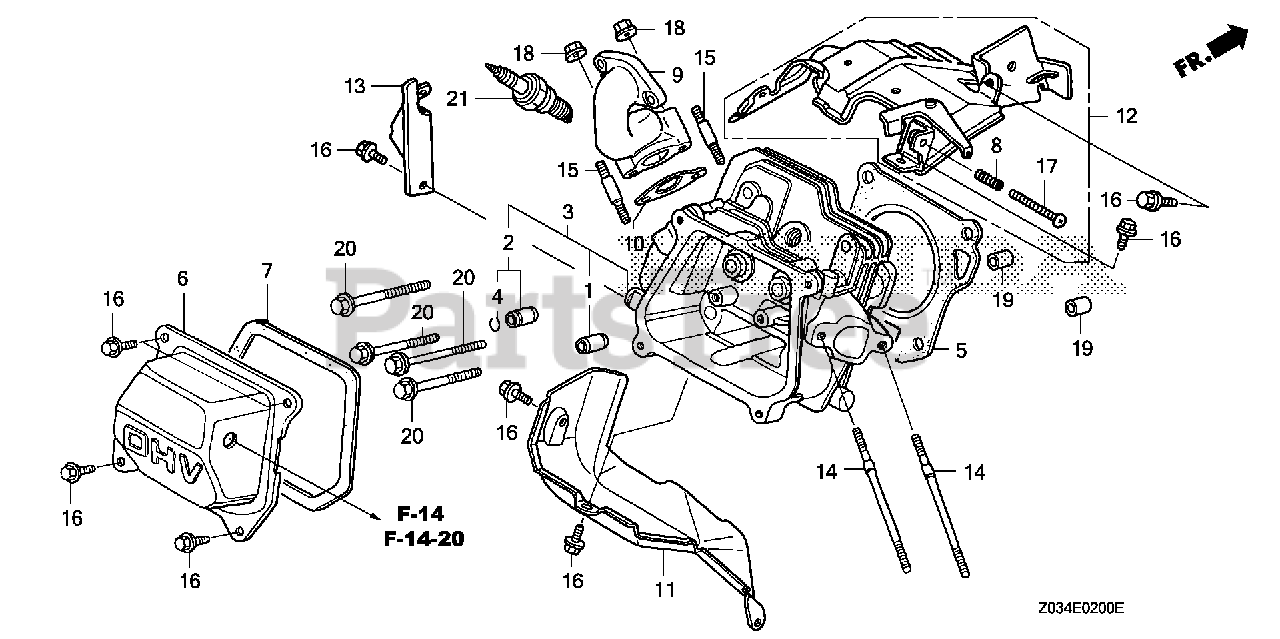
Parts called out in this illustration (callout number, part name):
1	GUIDE, VALVE (OVER SIZE)
2	GUIDE, EX. VALVE (OVER SIZE)
3	CYLINDER HEAD
4	CLIP, VALVE GUIDE
5	GASKET, CYLINDER HEAD (NIPPON LEAKLESS)
6	COVER, HEAD
7	GASKET, HEAD COVER
8	SPRING, CONTROL ADJUSTING
10	GASKET, MUFFLER
12	SHROUD (UPPER)
13	PLATE, AIR GUIDE
14	BOLT, STUD (6X104) (CT200)
15	BOLT, STUD (8X65) (CT200)
16	BOLT, FLANGE (6X12) (CT200)
17	SCREW, PAN (5X35)
18	NUT, FLANGE (8MM)
19	PIN, DOWEL (10X16)
20	BOLT, FLANGE (8X60)
21	SPARK PLUG (BPR5ES) (NGK)
21	SPARK PLUG (W16EPR-U) (DENSO)
21	SPARK PLUG (BPR6ES) (NGK)
21	SPARK PLUG (W20EPR-U) (DENSO)
